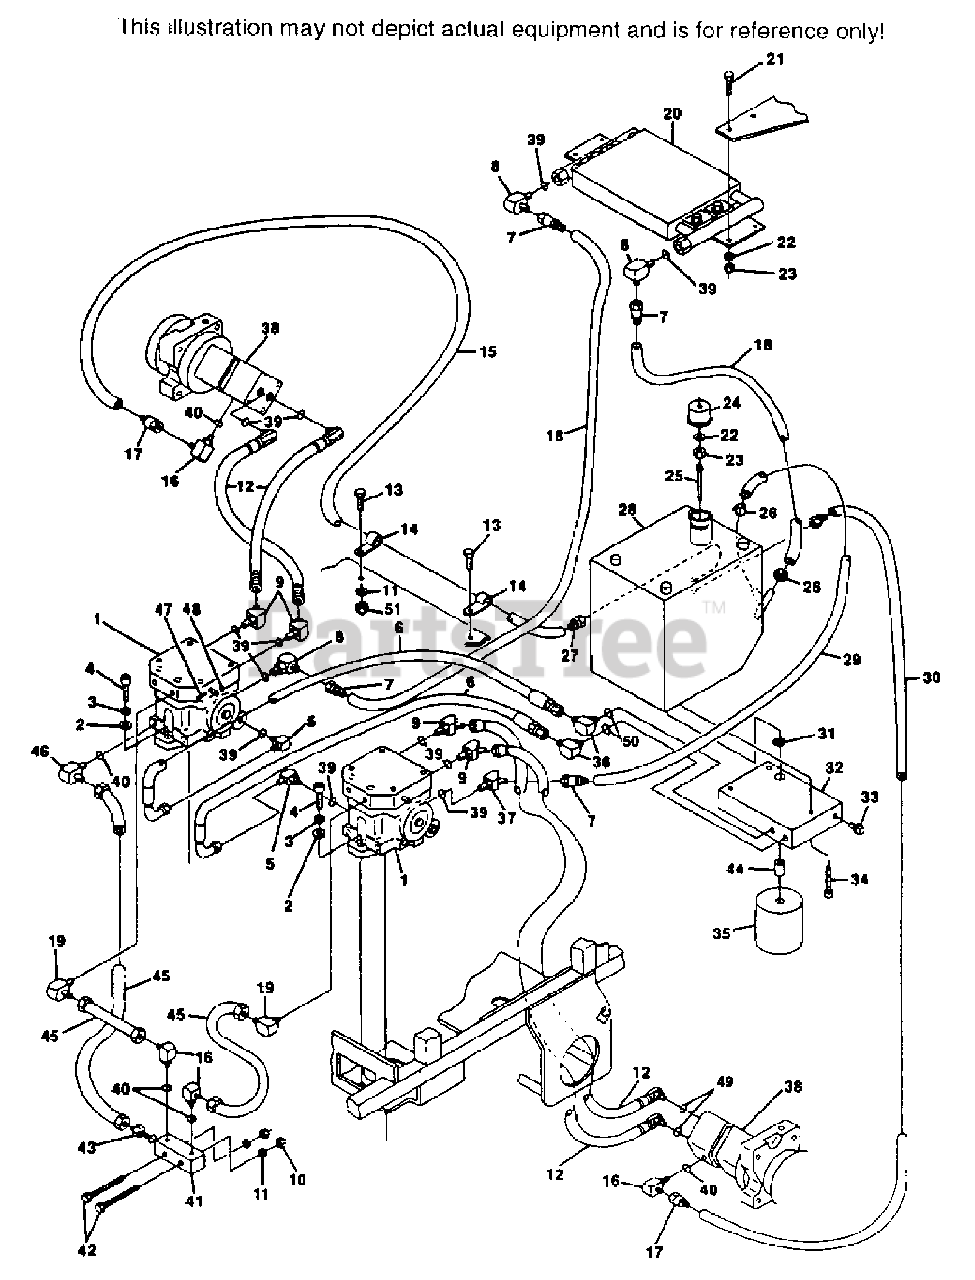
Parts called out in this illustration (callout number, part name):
1	PUMP, SUNDSTRAND
2	FLAT WASHER(.516 X .937 X .105)
4	CAPSCREW, SOCKET HD., 5/16-18 X 3/4"
5	ELBOW 90 DEG., 1-1/16-12 JIC TO 3/4-16 "O"
6	HOSE ASSEMBLY, PUMP SUCTION
7	COUPLING, 7/8-14 SAE FLARE TO 5/8 ID HOSE
8	ELBOW 90 DEG., 7/8-14 JIC TO 3/4-16 "O"
9	ELBOW 45 DEG., 3/4-16 JIC TO 3/4-16 "O"
10	1/4-20 ELASTIC STOP NUT
12	HOSE ASSEMBLY, PUMP TO MOTOR
14	HOSE CLAMP
15	HOSE, 1/4" ID - 31 1/2" LONG
16	ELBOW 90 DEG., 7/16-20 JIC TO 7/16-20 "O"
17	COUPLING, 7/8-14 SAE FLARE TO 1/4 ID HOSE
18	HOSE, 5/8" ID - 18-1/2" LONG
19	ELBOW 90 DEG. 1/8 NPT X 7/16-20JIC
20	OIL COOLER
24	CAP, OIL RESERVOIR
25	DIP STICK
26	HOSE CLAMP
27	COUPLING, 1/4 NPT TO 1/4 ID HOSE
28	OIL RESERVOIR
29	HOSE, 5/8" ID - 16" LONG
30	HOSE, 1/4" ID - 14 1/2" LONG
31	"O" RING, 1/8 X 1 ID
32	OIL MANIFOLD
33	PIPE PLUG, 1/2 NPT MAGNETIC
34	CAPSCREW, SOCKET HD., 3/8-16 X 2"
35	OIL FILTER
36	ELBOW 90 DEG.
37	ELBOW 45 DEG., 7/8-14 JIC TO 3/4-16 "O"
38	WHITE MOTOR
39	"O" RING, 3/32 X 5/8" ID
40	"O" RING 1/16 X 3/8" ID
41	E-Z RIDE VALVE
43	UNION TUBE, 7/16-20
44	NIPPLE, OIL FILTER
45	HOSE ASSEMBLY, E-Z RIDE VALVE
48	HEX NUT, 1/4-20 ELASTIC STOP
